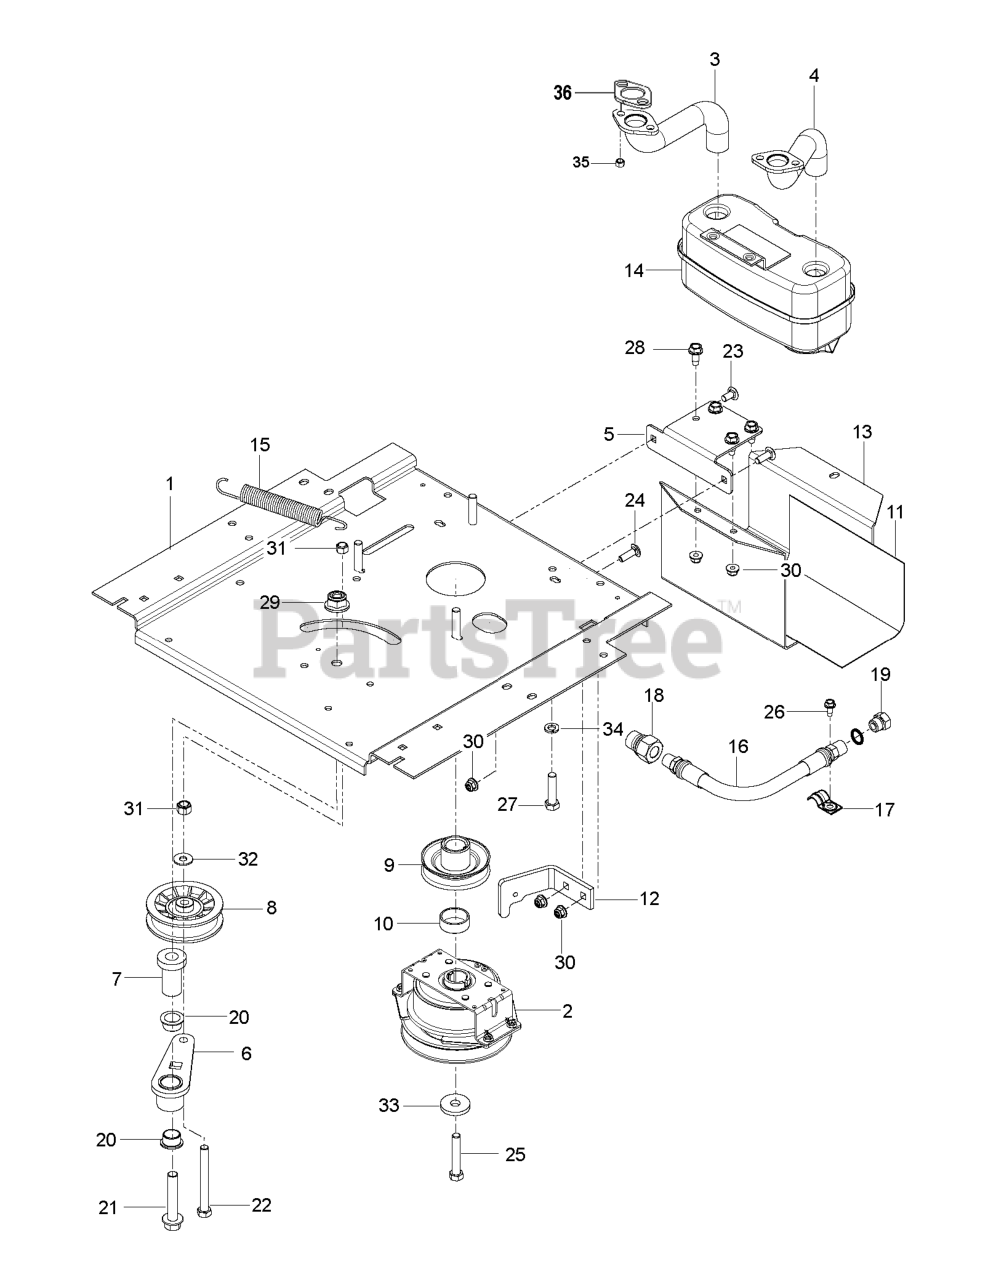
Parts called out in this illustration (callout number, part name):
1	PLATE.ENGINE.PNT.23"FRAME.EDIP
2	CLUTCH.OGURA.5.0PD.GT1.5A-EH07
3	TUBE.EXHAUST.RH.FR961/FR730
4	TUBE.EXHAUST.LH.FR961/FR730
5	BRACKET MUFFLER MS431BLK
6	ARM IDLER
7	SPINDLE.IDLER
8	PULLEY, IDLER RAKE & ZTR
9	PULLEY.ENGINE
10	SPACER.SPACER.625 W/OGURA.LCC
11	HEAT SHIELD
12	CLUTCH.STOP.OGURA LCC.BLACK
13	GUARD.MUFFLER.WO.TOW.HITCHX431
14	MUFFLER ASM TWIN
15	SPRING, DECK DRIVE
16	HOSE.ASSEMBLY.OIL.DRAIN
18	ADAPTER, OIL DRAIN
19	PLUG OIL DRAIN
20	BEARING.FLANGED.PLASTIC.3/4ID
21	Bolts
21	BOLT.FLANGE.1/2-13 X 2.75.GRD5
22	Screws
22	HCS 3/8-16X3-1/2 TAPBLT GR5 ZD
23	BOLT 5/16C X 3/4" CARRIAGE
23	GSPW Bolts
24	RHSNB 5/16C X 1
25	Bolts
25	CLUTCH BOLT7/16-20X2.5 GR524HR
25	CLUTCH BOLT7/16-20X3.5 GR524HR
26	SCR 1/4-20X5/8 HEX SELF TAP ZD
26	Screws
27	BOLT
27	Bolts
28	SCREW.THDROL.5/16-18X3/4.TTY
28	Bolts
29	NUT 1/2-13 HEX FLANGE NYLOK CL
29	NUT, 1/2-13 HEX FLG NYLOC ZD
30	NUT HEXAGON FLANGE 5/16-18 ST
30	5/16-18 NYLOC FLANGE NUT
31	NUT 3/8-16 NYLOC
32	GSPH
32	WASHER 5/16 FLAT
32	WASHER.5/16.FLAT.STE.STD.
34	LOCKWASHER
34	SLW 3/8 STD
34	Washers
35	NUT.HEX.FLANGE.TOPLOCK
36	GASKET
